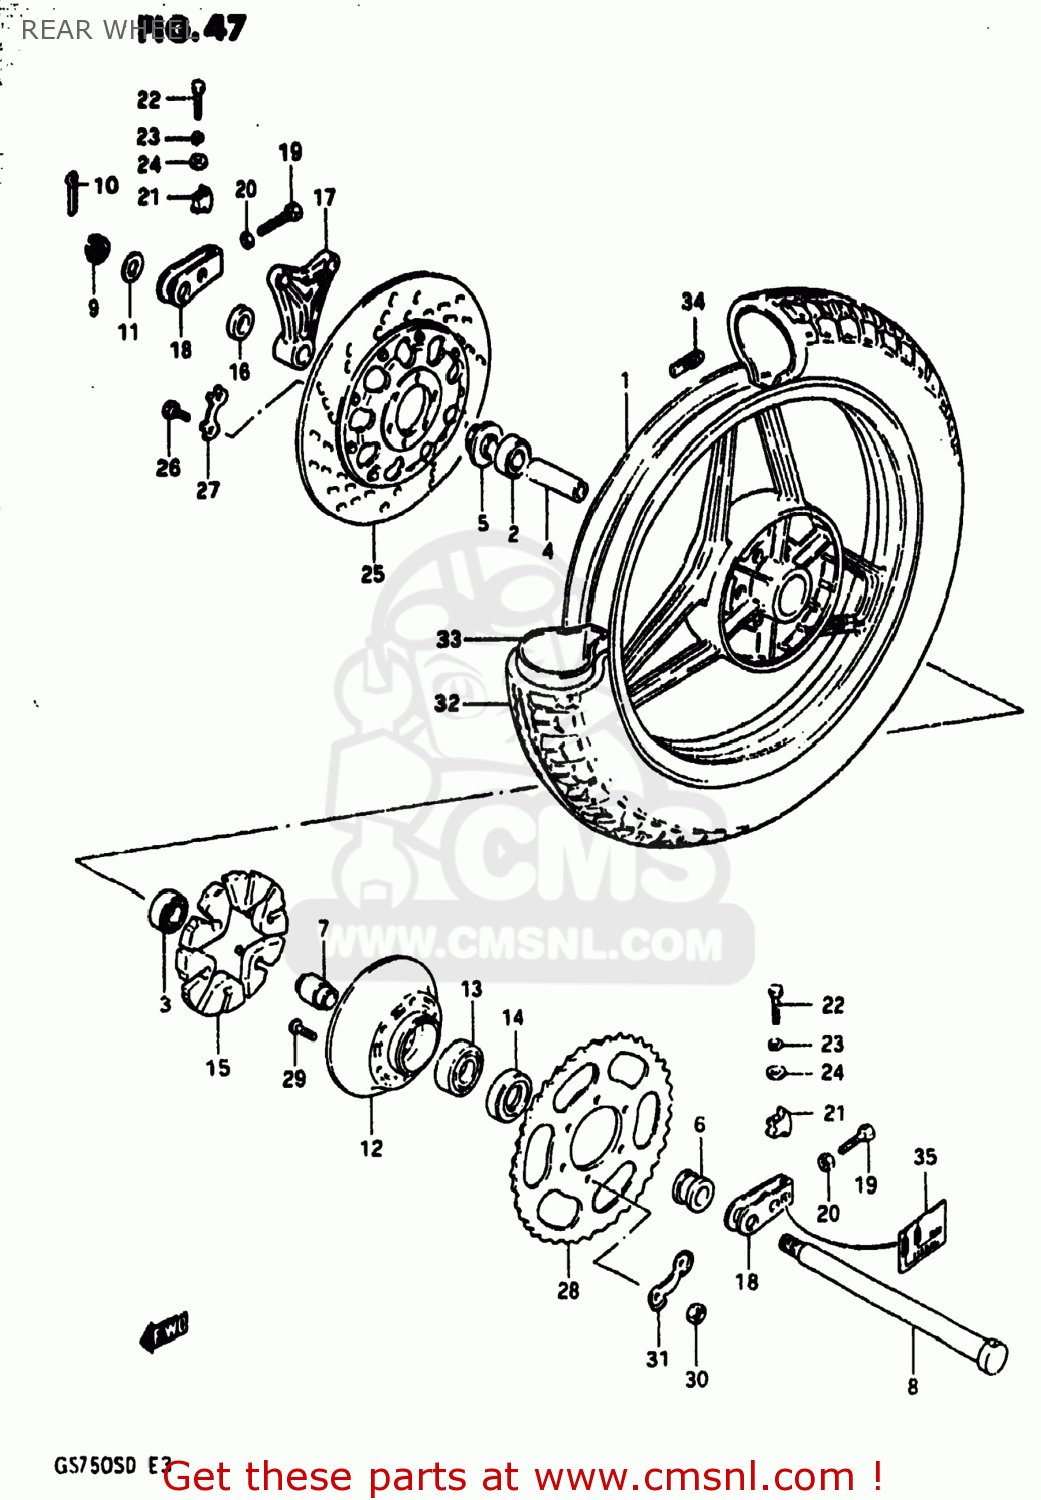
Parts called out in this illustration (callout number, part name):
1	WHEEL, REAR (18X2.15) (BLACK)
2	BEARING WHEEL REAR(20X47X14)
3	BEARING, LH
4	SPACER,REAR HUB BEARING
5	SPACER,REAR AXLE
6	SPACER(20X33X28.3)
7	SPACER,REAR HUB BEARING
8	AXLE,REAR
9	NUT 18MM
10	PIN,COTTER
11	WASHER(19X34X4)
12	DRUM,REAR SPROCKET MOUNT
13	BEARING
14	SEAL,OIL(33X62X7)
15	ABSORBER,REAR HUB SHOCK
16	SPACER (20X38X17)
17	BRACKET,RR,CALIPER
18	ADJUSTER,CHAIN
19	BOLT
20	NUT
21	SUPPORTER,CHAIN ADJUST
22	BOLT
23	LOCK WASHER
24	WASHER
25	DISC,RR BRAKE
26	BOLT(8X30)
27	WASHER
28	SPROCKET,RR
29	BOLT
30	NUT
31	WASHER
32	TIRE
33	TUBE,INNER
34	BALANCER,WHEEL
35	LABEL,CHAIN WEAR INDICATOR
